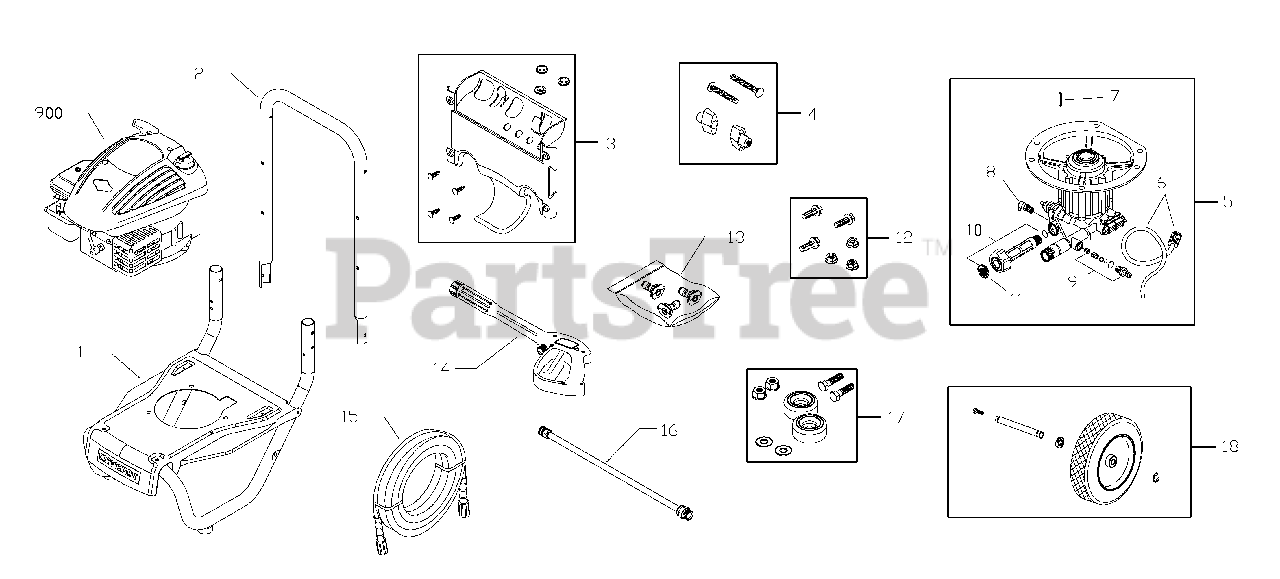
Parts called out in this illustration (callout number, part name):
2	Handle
3	Kit, Billboard w/Decals
4	Kit, Handle Connector
6	Kit, Chemical Hose
8	Valve, Thermal Relief
9	Kit, Chemical Injection
10	Kit, Water Inlet
12	Kit, Pump Mounting Hardware
14	Gun
15	Hose
16	Extension, QC
17	Kit, Vibration Mount
18	Kit, Wheel
900	Engine
